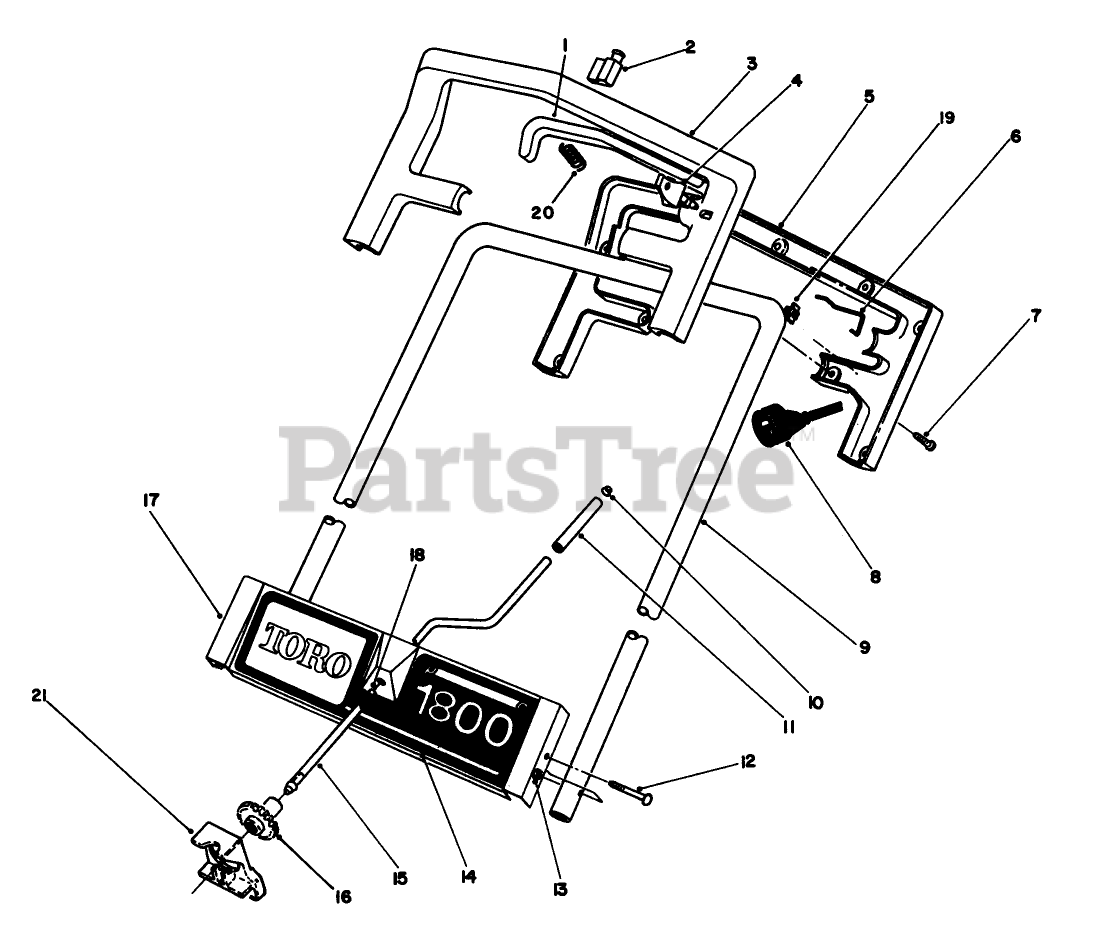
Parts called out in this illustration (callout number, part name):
1	SWITCH BAR - 1800
10	PUSHNUT-CAP, WASHER
11	SLEEVE, CHUTE CRANK
12	SCREW-HH
13	NUT-LOCK, NI
15	ROD, CHUTE CRANK
16	GEAR-CHUTE CRANK
18	NYLINER
20	SPRING-COMPRESSION
21	1800 PC-GEAR BRAKE
